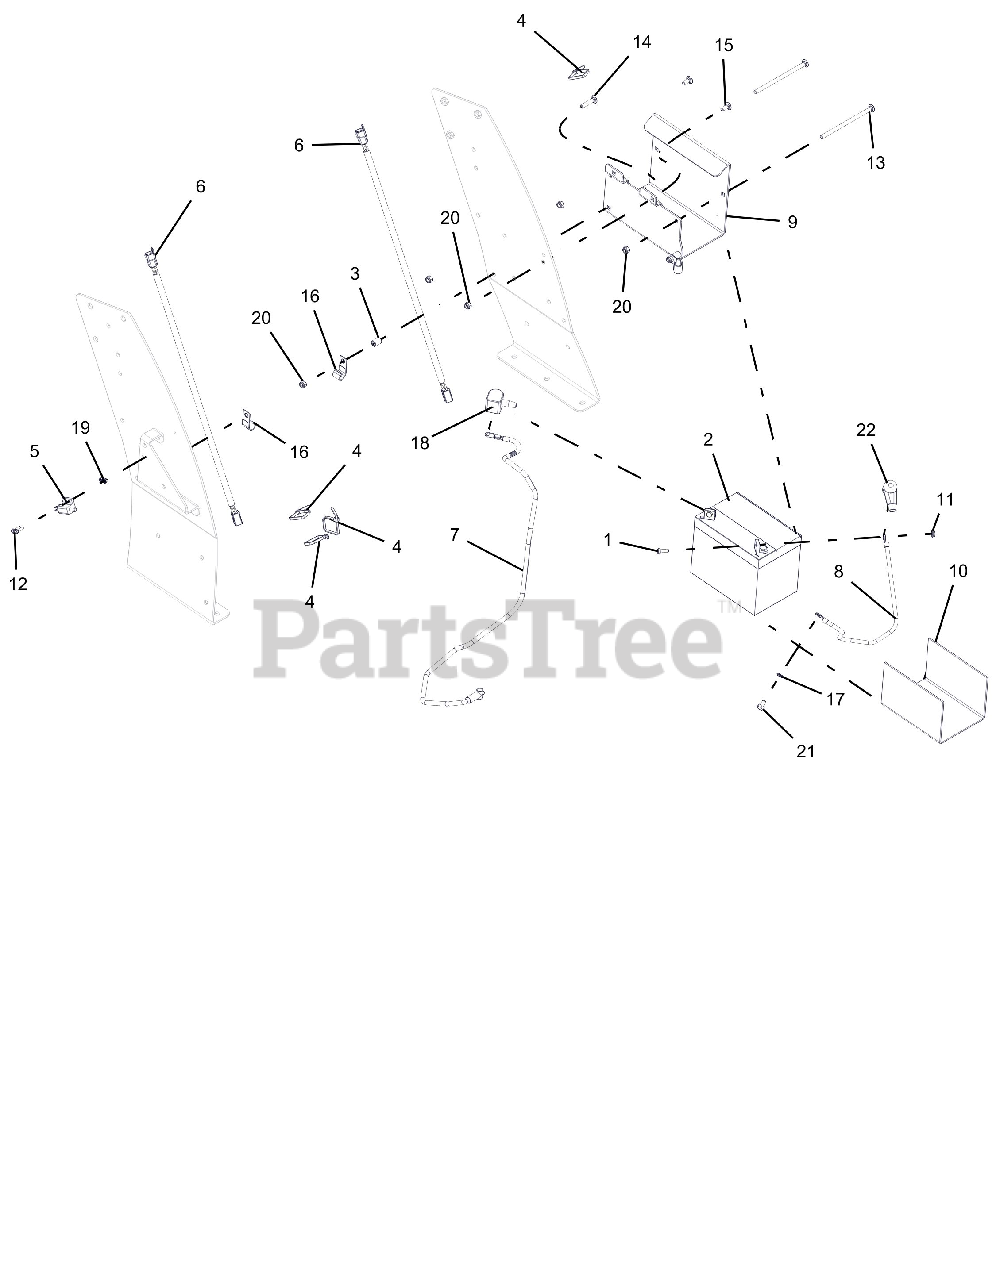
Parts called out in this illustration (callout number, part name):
1	BLT-HEX .25-20X.75 GR5 YWZC
2	BATTERY, 12V-U1-CCA270MIN
3	BUSHING, .364X.540X.700 Y
4	CABLE TIE, .19 X 14.4
5	SWITCH- DOUBLE POLE N.O./N.O.
6	ADAPTER-HARNESS-PRO WALK HYDRO
7	CABLE, BATTERY - 42" POSITIVE
8	CABLE, NEGATIVE BATTERY 35.00"
9	TRAY, BATTERY ELEC
10	STRIP, RUBBER
11	@NUT-SPNLK-FLG .25-20 YWZC
12	@SCR-MCH 10-24X.75 HWH YWZC
13	BLT-RDHDSQNK .31-18X6.00 G5 Y
14	BLT-RDHDSQNK .31-18X1.50 G5 YWZC
15	BLT-RDHDSQNK .31-18X.75 G5 YWZC
16	P-CLIP, .500 INSULATED
17	WSHR-LK-EXT .326X.599X.031 YWZC REV
18	BOOT, POS BATTERY TERMINAL WLK
19	NUT-KEPS 10-24
20	NUT-LK-NYL .312-18 YWZC
21	@BLT-HEX M8 X 1.25X14 YWZC
22	BOOT, BATTERY TERMINAL BLACK
